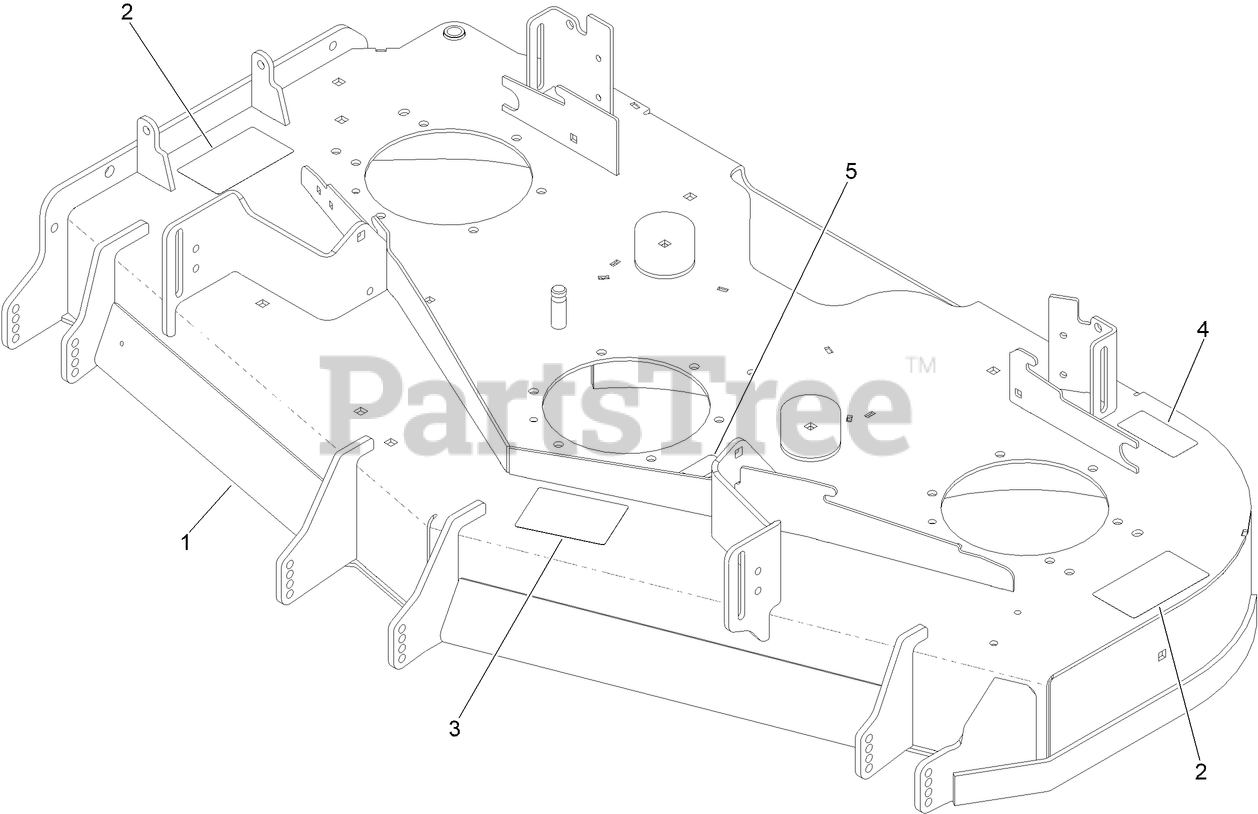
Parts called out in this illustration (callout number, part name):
1	Deck ASM W/Decals
2	DECAL-DANGER
3	DECAL-SCALP, ANTI
4	DECAL-BOLT TORQUE
5	DECAL-ROUTING, BELT
